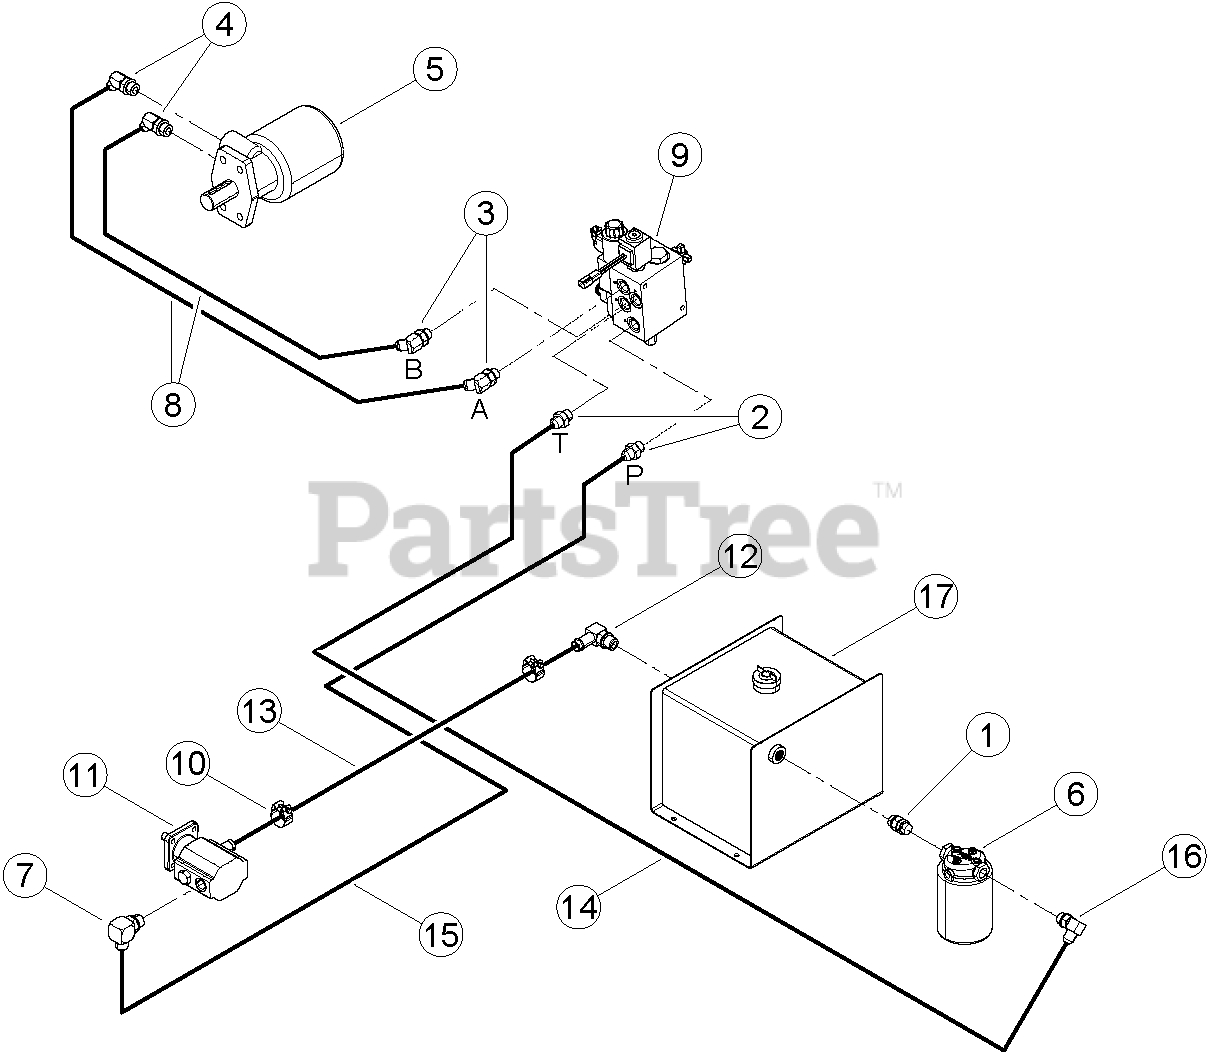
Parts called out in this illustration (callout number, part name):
1	ADAPTER, -8 MORING / -8 MORING ADJ
2	ADAPTER, -8 MORING / -8 MJIC
3	ADAPTER, -8 MORB / -8 MJIC 45 DEG.
4	ADAPTER, -10 MORING / -8 MJIC 45 DEG.
5	MOTOR, 45 CU. IN. HYDRAULIC
6	FILTER, SPIN-ON
7	ADAPTER, -10 MORING / -10 MJIC 90 DEG.
8	HOSE, .375 X 36 -8 FMJIC / -8 FMJIC
9	ASSEMBLY, CHIPPER VALVE
10	CLAMP, 1-5/32 TO 7/32 OD RANGE T-BOLT
11	PUMP, 2 STAGE CW HI/LO 0.605 DISP.
12	ADAPTER, -10 MORING / .75 90 DEG.
13	HOSE, .75 ID. X 38 IN. 100R4 HYD.
14	HOSE, .50 X 84 -8 FMJIC / -8 FMJIC
15	HOSE, .50 X 66 -8 FMJIC / -10 FMJIC 90 DEG.
16	ADAPTER, -8 MORING / -8 MJIC 90 DEG.
17	WELDMENT, TANK HYDRAULIC 3.25 GAL.
